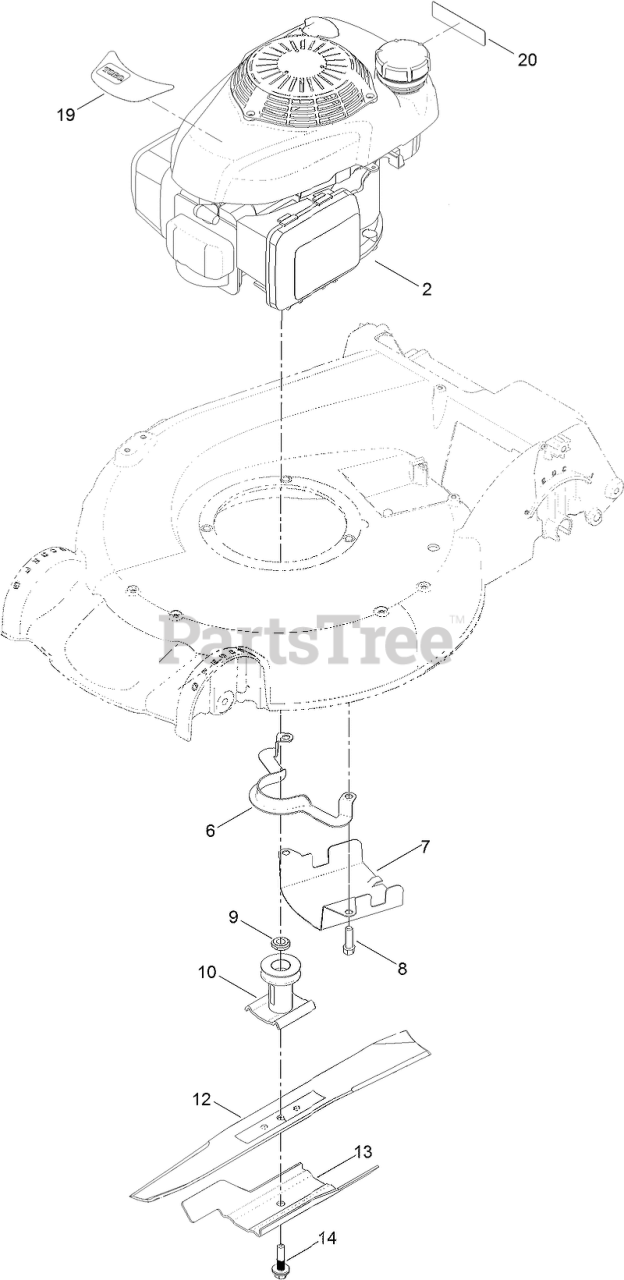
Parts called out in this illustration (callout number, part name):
6	GUIDE-BELT
7	SHIELD-GRASS
8	SCREW-TAPTITE
9	Spacer-Driver
10	DRIVER-BLADE
12	BLADE-RECYCLING
13	Accelerator-Blade
14	BOLT-BLADE
19	DECAL-SHROUD, HONDA
20	DECAL-ARRESTER, SPARK
